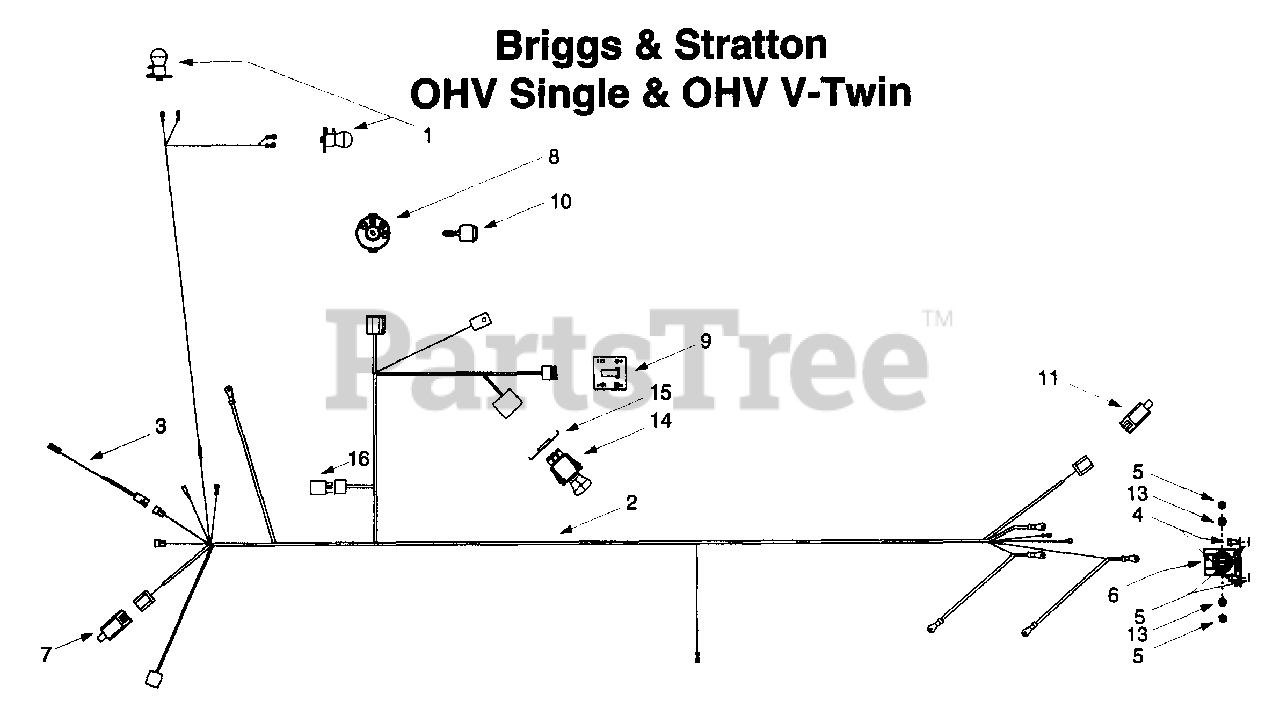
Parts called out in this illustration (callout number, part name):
1	Bulb/Socket Headlight Assembly
2	Wiring Harness
3	Harness Adapter, #18 x 5"
4	Self Tapping Screw, 1/4-20 x .5
5	Hex Nut, 1/4-20
6	Solenoid, 12-volt, 100 Amp
7	Snap Mount Safety Interlock Switch (Brake)
8	Ignition Switch
9	Indicator Monitor w/o Hour Meter
10	Ignition Key W/Plastic Cover
11	Safety Plunger Switch (Seat)
13	Lock Washer, 1/4
14	Electric PTO Switch
15	Retainer Bracket
16	Electric PTO Relay
